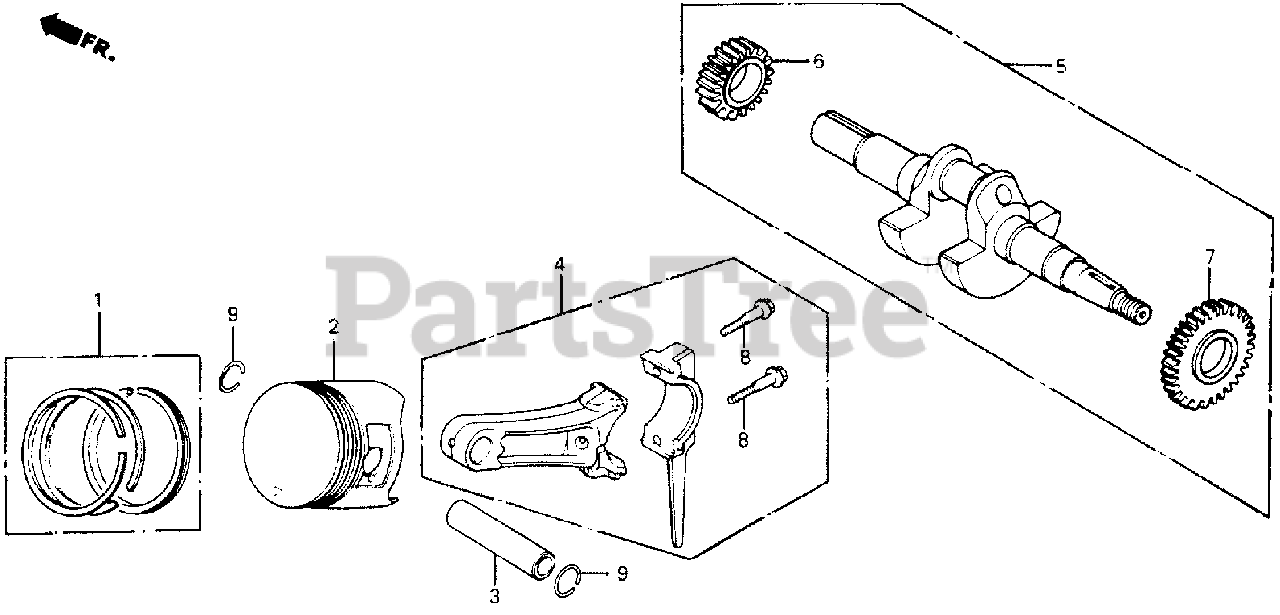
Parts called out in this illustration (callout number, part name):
1	RING SET, PISTON (STD)
1	RING SET, PISTON (OS 0.25) Use up to Engine SN 2582392.
1	RING SET, PISTON (OS 0.50) Use from Engine SN 2582392.
1	RING SET, PISTON (OS 0.50) Use up to Engine SN 2582392.
1	RING SET, PISTON (0.75) Use up to Engine SN 2582392.
1	RING SET, PISTON (OS 0.25)
1	RING SET, PISTON (OS 0.50)
1	RING SET, PISTON (0.75)
2	PISTON (STD)
2	PISTON (OS 0.25) Use up to Engine SN 2582392.
2	PISTON (OS 0.25) Use from Engine SN 2582393.
2	PISTON (OS 0.50) Use up to Engine SN 2582392.
2	PISTON (OS 0.50) Use from Engine SN 2582393.
2	PISTON (0.75)
3	PIN, PISTON
4	ROD ASSY., CONNECTING (US 0.25)
4	ROD ASSY., CONNECTING
5	CRANKSHAFT (S-TYPE)
6	GEAR, TIMING
7	GEAR, GOVERNOR DRIVE
8	BOLT, CONNECTING ROD
9	CLIP, PISTON PIN (18MM)
